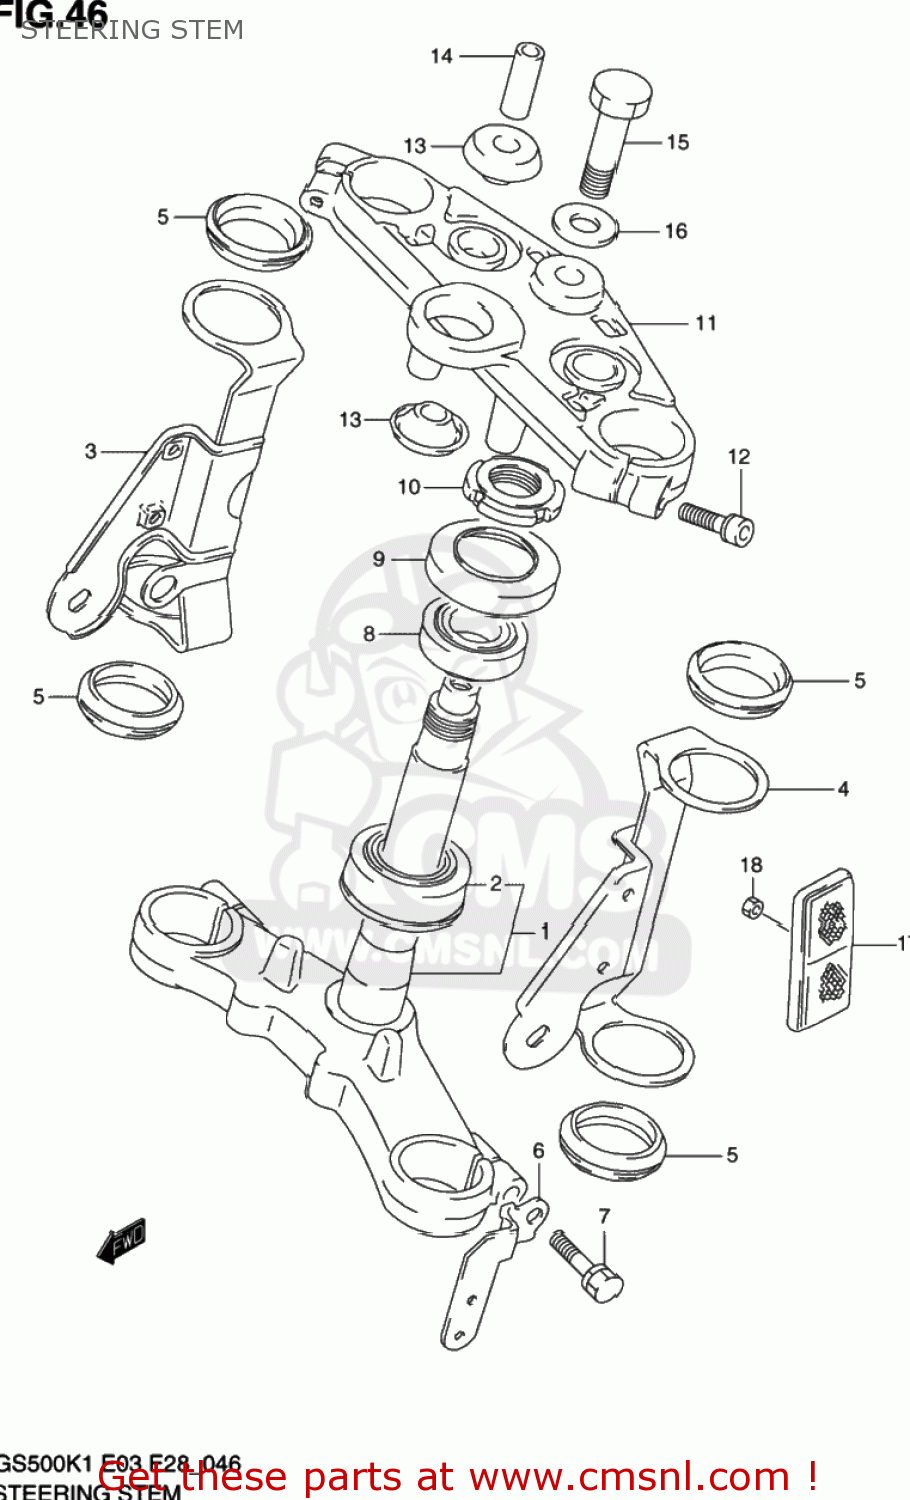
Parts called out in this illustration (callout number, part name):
1	STEM,STEERING
2	BEARING(30X55X17)
3	BRACKET,HEADLAMP,R
4	BRACKET,HEADLAMP,L
5	CUSHION,HEADLAMP BRACKET
6	BRACKET,FR SIDE RR,R
7	BOLT,STEERING STEM
8	BEARING(25X47X15)
9	SEAL,STEERING UPR DUST
10	NUT,STEERING STEM(25X44X10)
11	HEAD,STEERING STEM
12	BOLT
13	CUSHION,UPR BRACKET
14	SPACER,STEERING STEM HEAD
15	BOLT
16	WASHER,STEM HEAD(10.5X30X3.2)
17	REFLEX REFLECTOR,FR SIDE
18	NUT
